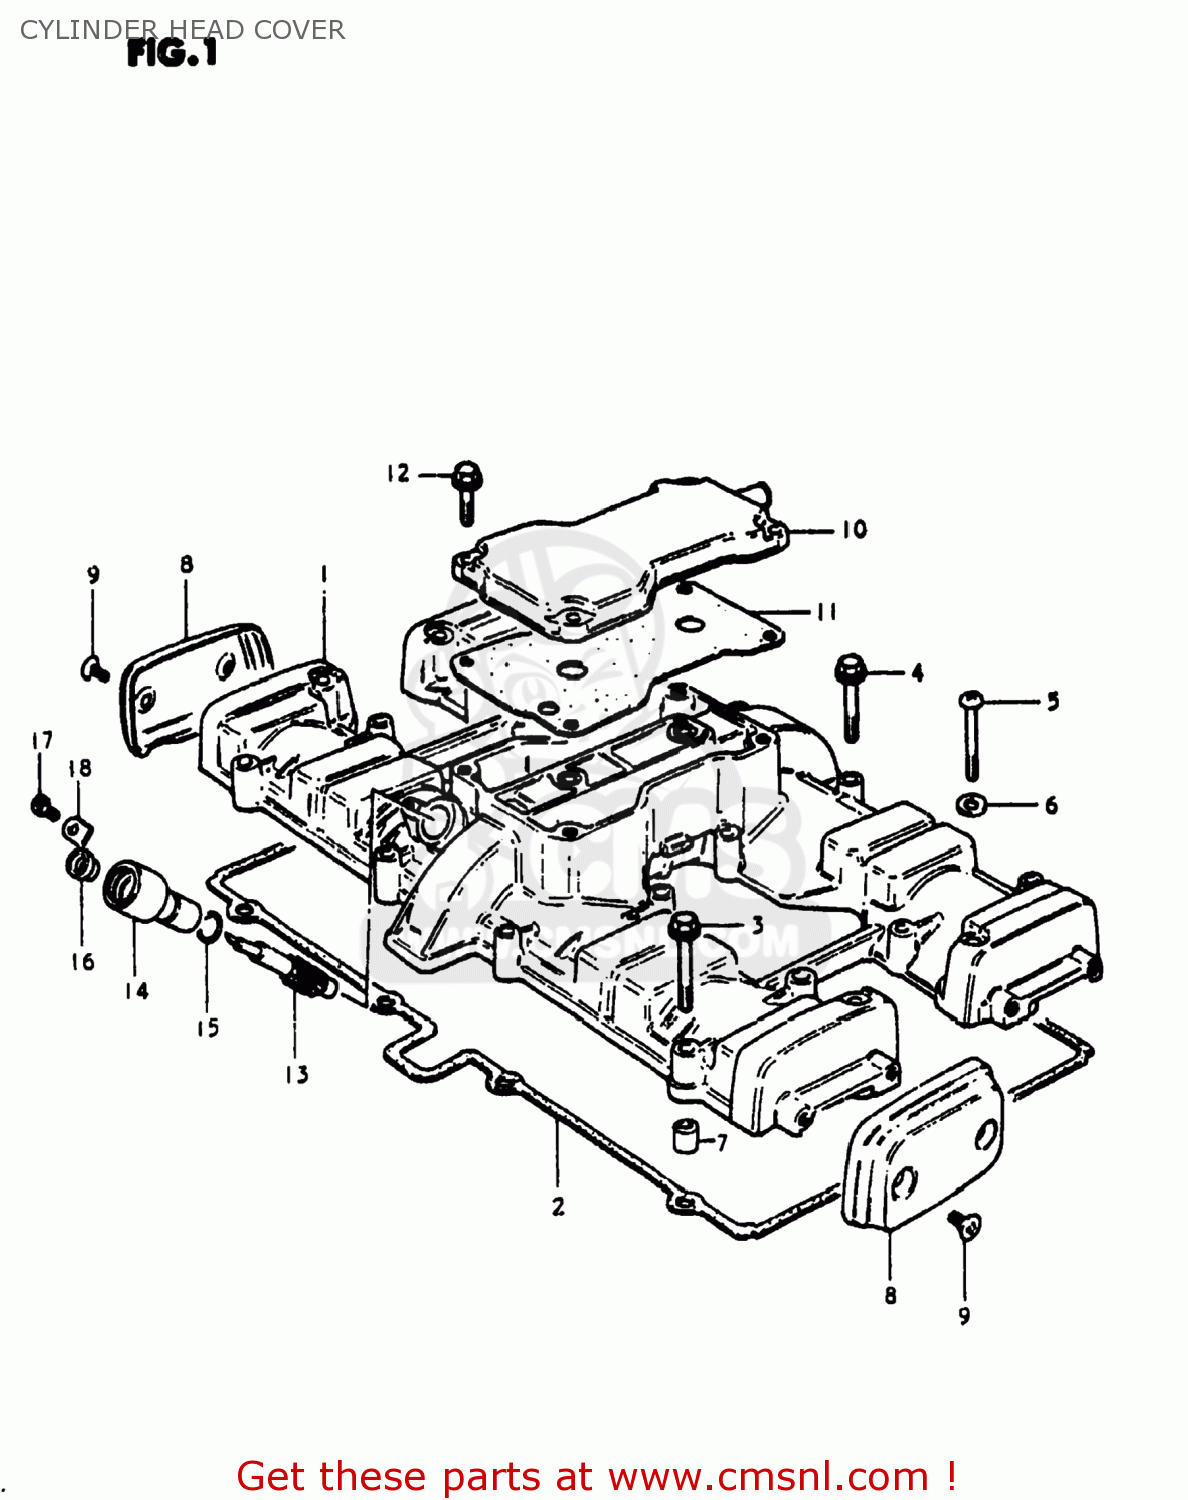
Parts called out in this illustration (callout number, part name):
1	COVER,CYLINDER HEAD
2	GASKET,CYLINDER HEAD COVER (MCA)
3	BOLT
4	BOLT 6X35
5	SCREW 6X40
6	GASKET (NAS)
7	PIN(6.2X8X11)
8	CAP,CYLINDER HEAD COVER
9	SCREW 5X12
10	COVER,BREATHER
11	GASKET (MCA)
12	BOLT,REAR
13	GEAR,TACHOMETER DRIVEN
14	SLEEVE,TACHOMETER DRIVE
15	SEAL,TACHOMETER DRIVEN
16	SEAL,OIL(5X12X8)
17	SCREW(5X12)
18	PLATE,TACH DRIVE GEAR SLEEVE
